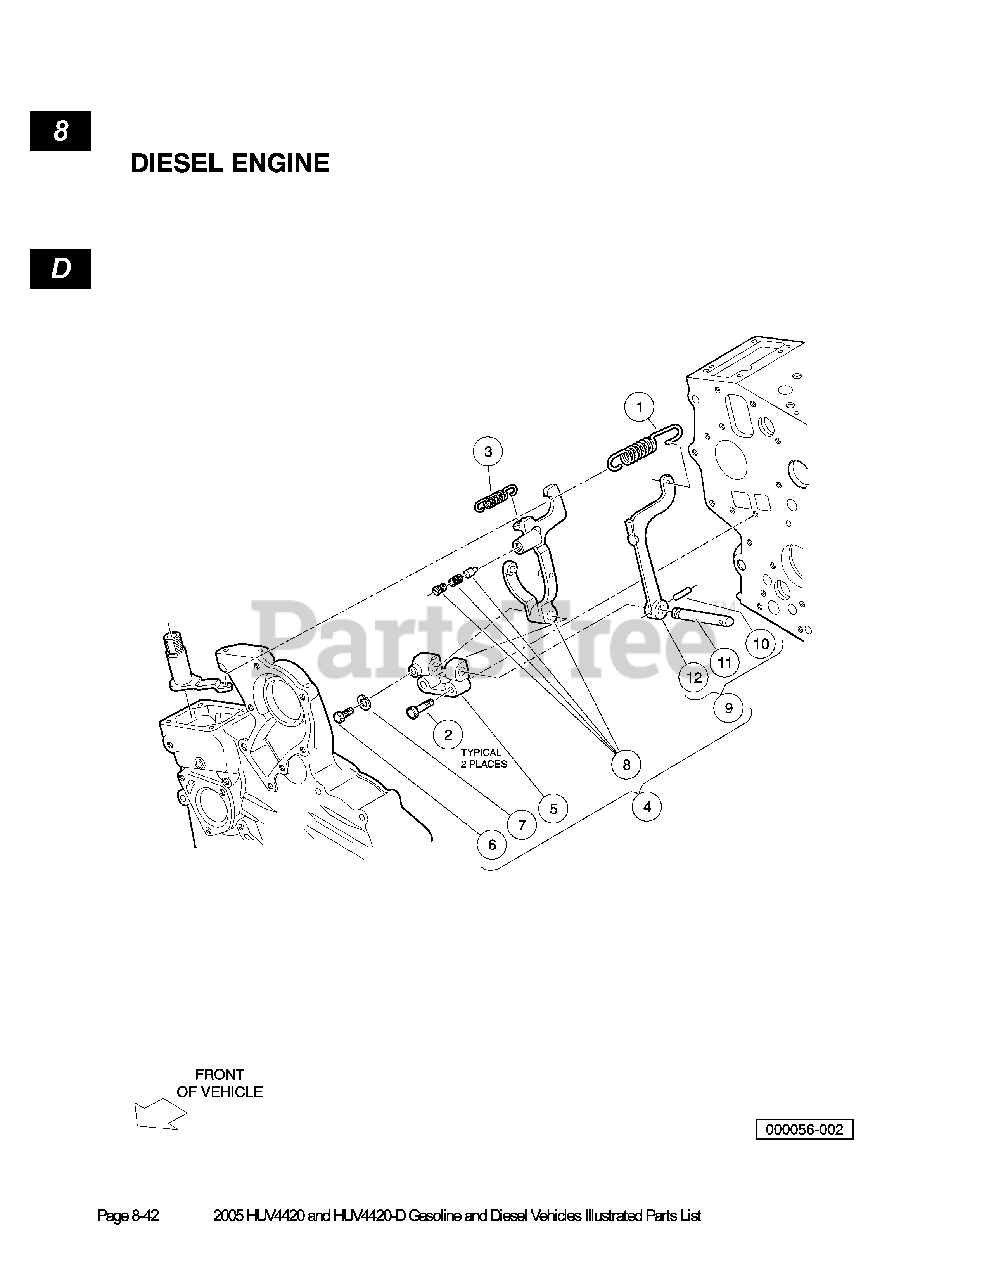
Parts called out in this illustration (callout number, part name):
1	Spring, Governor
2	Bolt, M5 X 0.75 X 25
3	Spring, Start
4	Assembly, Governor Fork
5	Holder, Fork Lever
6	Bolt, M5 X 0.75 X 11
7	Washer, Spring, M5
8	Lever, Fork, Middle, D722 CB
9	Assembly, Governor Fork Level, Lower, D722 CB
10	Pin, Spring
11	Shaft, Fork Lever
12	Lever, Fork, End, D722 CB
